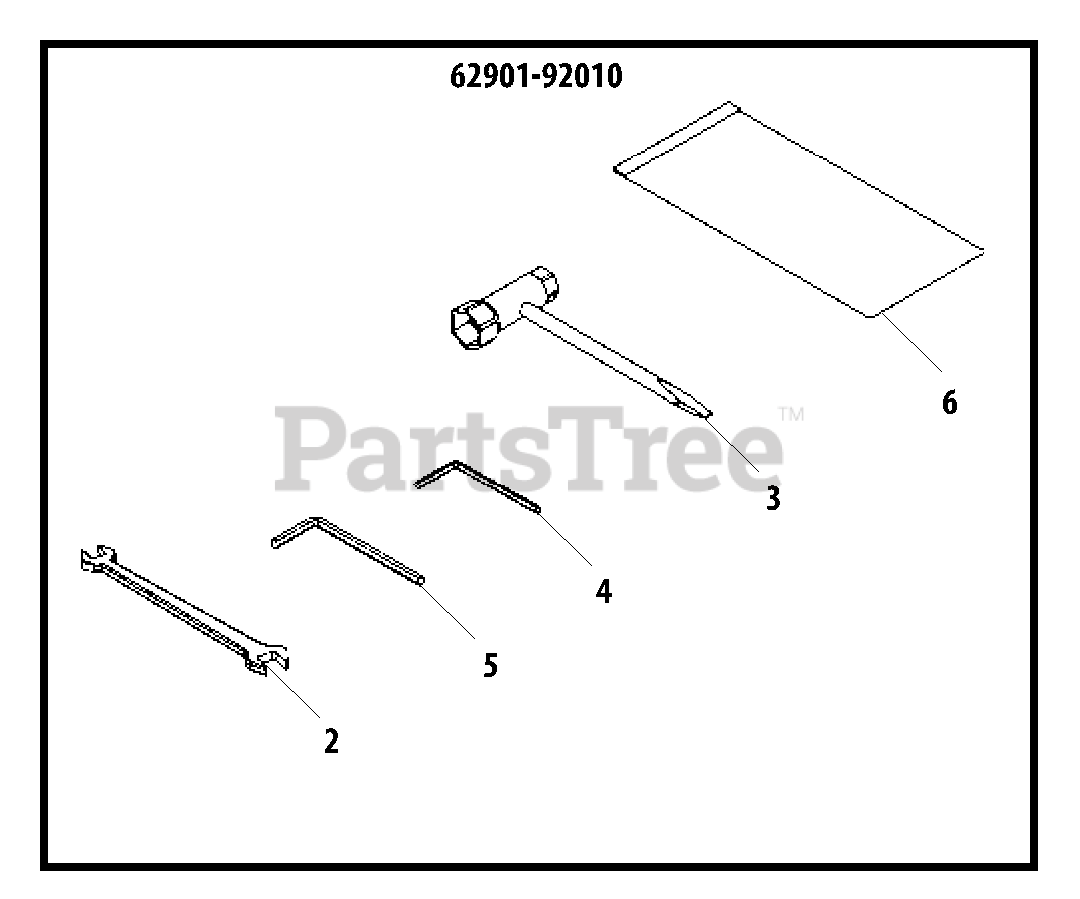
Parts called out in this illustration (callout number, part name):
2	SPANNER 8×10
3	T-WRENCH 16×13
4	WRENCH, ALLEN 3 MM
5	WRENCH, ALLEN 4 MM
6	BAG, TOOL
62901-92010	TOOL KIT, SERVICE
